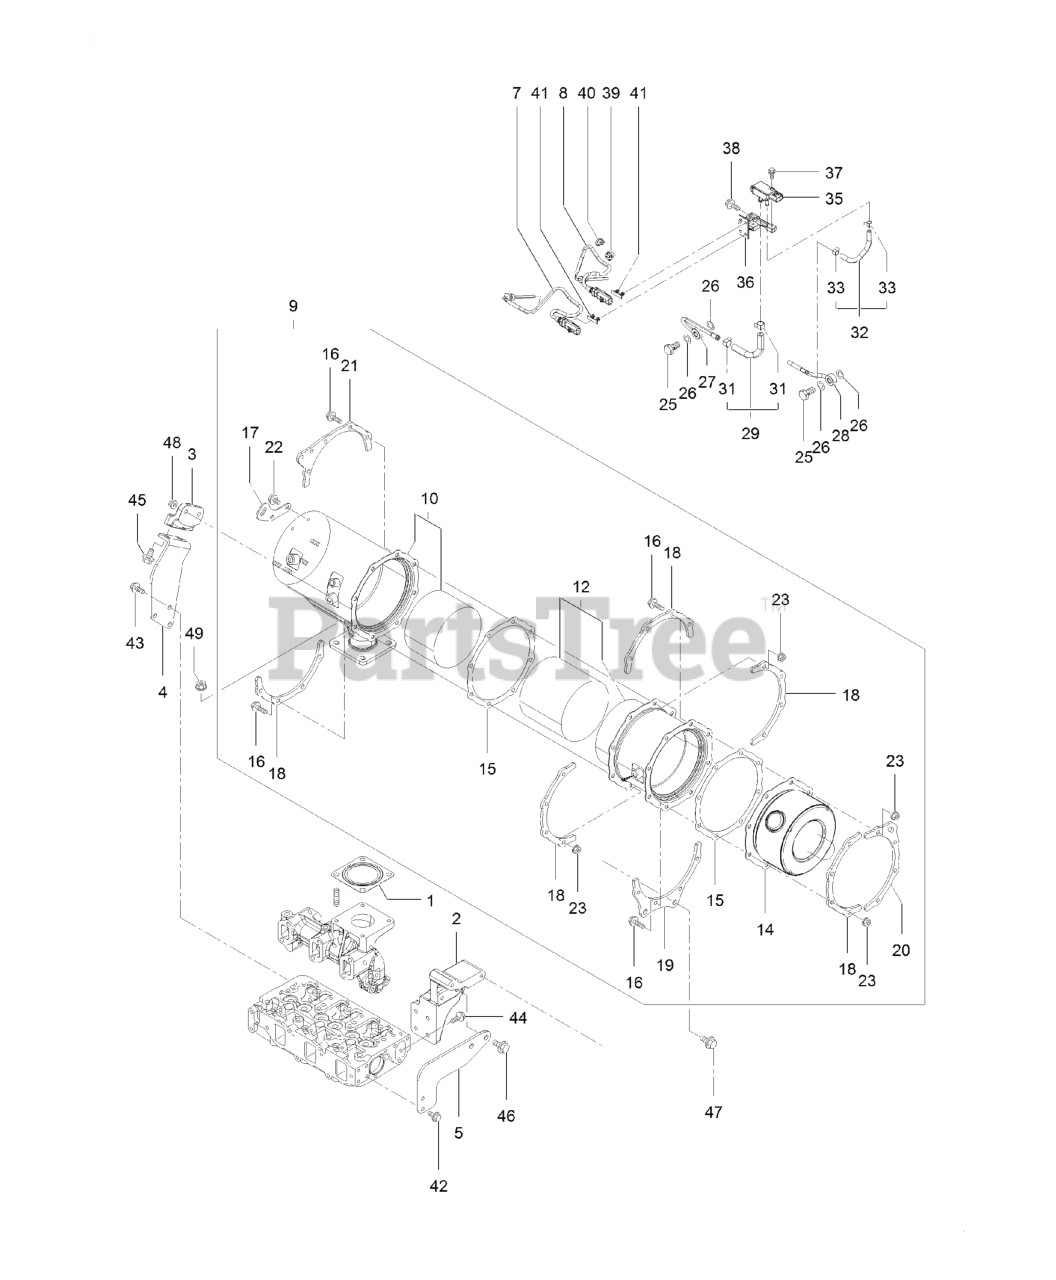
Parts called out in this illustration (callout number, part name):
1	GASKET-SILENCER
2	STAY-D P F
3	STAY-D P F
4	STAY-D P F
5	STAY-D P F
7	SENSOR-TEMP, EXHAUST
8	SENSOR-TEMP, EXHAUST
9	D P F ASM
10	CASE-D O C
12	CASE-FILTER, SOOT
14	SILENCER-D P F
15	GASKET-D P F
17	LIFTER-D P F
18	STIFFENER-D P F, A
19	STIFFENER-D P F, B
20	STIFFENER-D P F, C
21	STIFFENER-D P F, C
25	BOLT-JOINT, PIPE
26	GASKET-SENSOR
27	SENSOR PIPE ASM
28	SENSOR PIPE ASM
29	EXHAUST HOSE ASM
31	Clip-Hose
32	EXHAUST HOSE ASM
33	Clip-Hose
35	SENSOR-PRESSURE
36	BRACKET-SENSOR
39	BAND-CLIP
41	CLIP-CONNNECTOR
42	BOLT
43	BOLT
